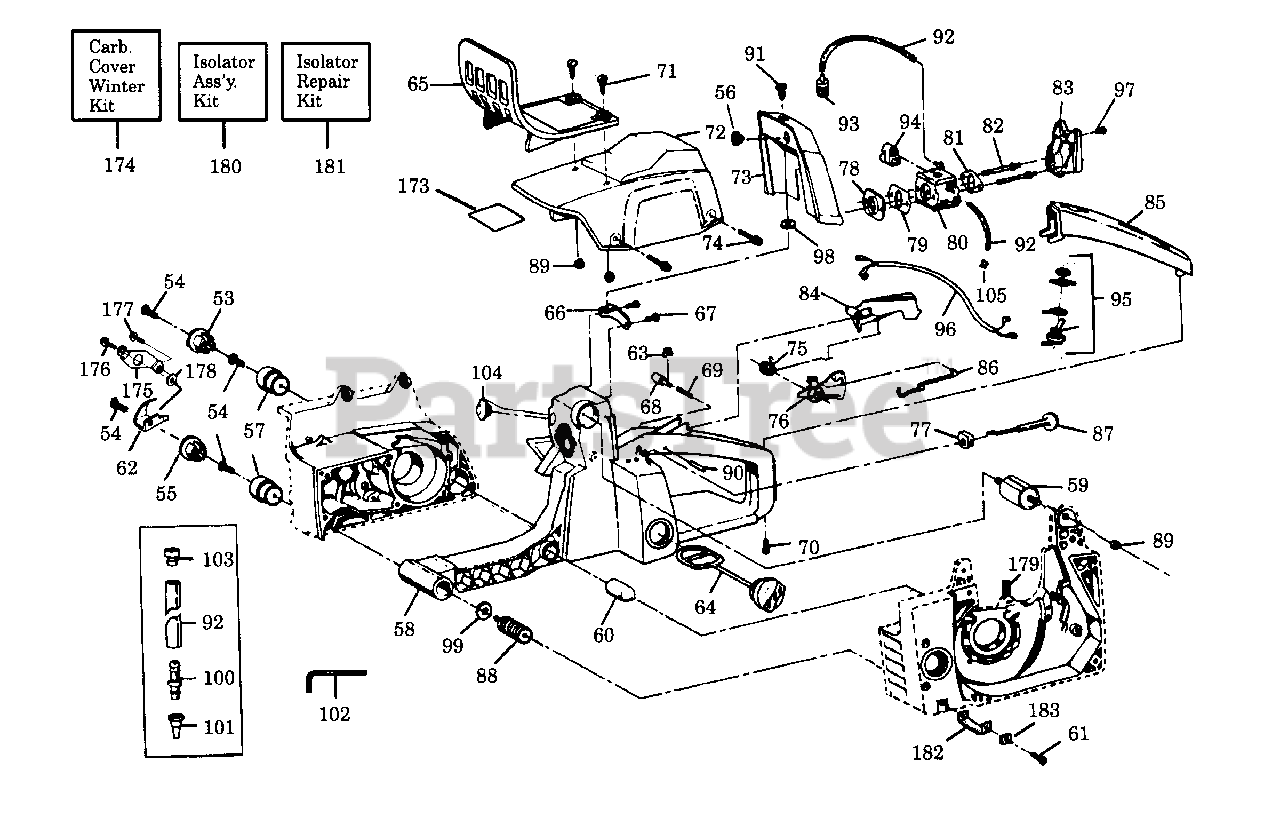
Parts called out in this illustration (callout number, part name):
53	Retainer Mount
55	Chain Catcher Retainer-See Serv. Ref. 1
56	Bumper-Carb. Cover
57	Lower Isolator
59	Cylindrical Mount
60	Isolator Limiter
61	Type II
62	Chain Catcher- See Serv.Ref. 1
63	"C" Clip
64	Fuel Cap Ass'y.
65	Handguard - See also key no. 172-pg.3
68	(Two piece design)
68	(One piece design)
69	Throttle Lock Spring
72	Model 2700,2800,3000
72	Model 3100,3300
73	Carburetor Cover
74	Screw
75	Trigger Latch Spring
76	Throttle Trigger
79	Gasket Set
80	Carburetor (HDA-49)
81	Air Filter Plate
82	Carb. Mounting Stud
83	Model 3000,3100,3300
83	Model 2700,2800
84	Throttle Lockout
85	Rear Handle Cover
86	Throttle Wire
87	Choke Knob
90	Dowel Pin
92	Fuel Line Kit (Bulk 8133)
93	Fuel Filter Ass'y.
95	Switch Kit
96	Lead Wire Ass'y.
97	Screw
98	Screw Retainer
99	Washer-Type II Only
100	Vent Fitting
101	Check Valve
102	Hex Key
104	Plug-Air Box
173	Reflector
174	Carb. Cover Winter Kit
179	Impulse Fitting
180	Isolator Ass'y. Kit-Type II Only
181	Isolator Repair Kit-Type II Only
182	AV Strap-Type II Only
183	Strap Retainer Plate-Type II Only
